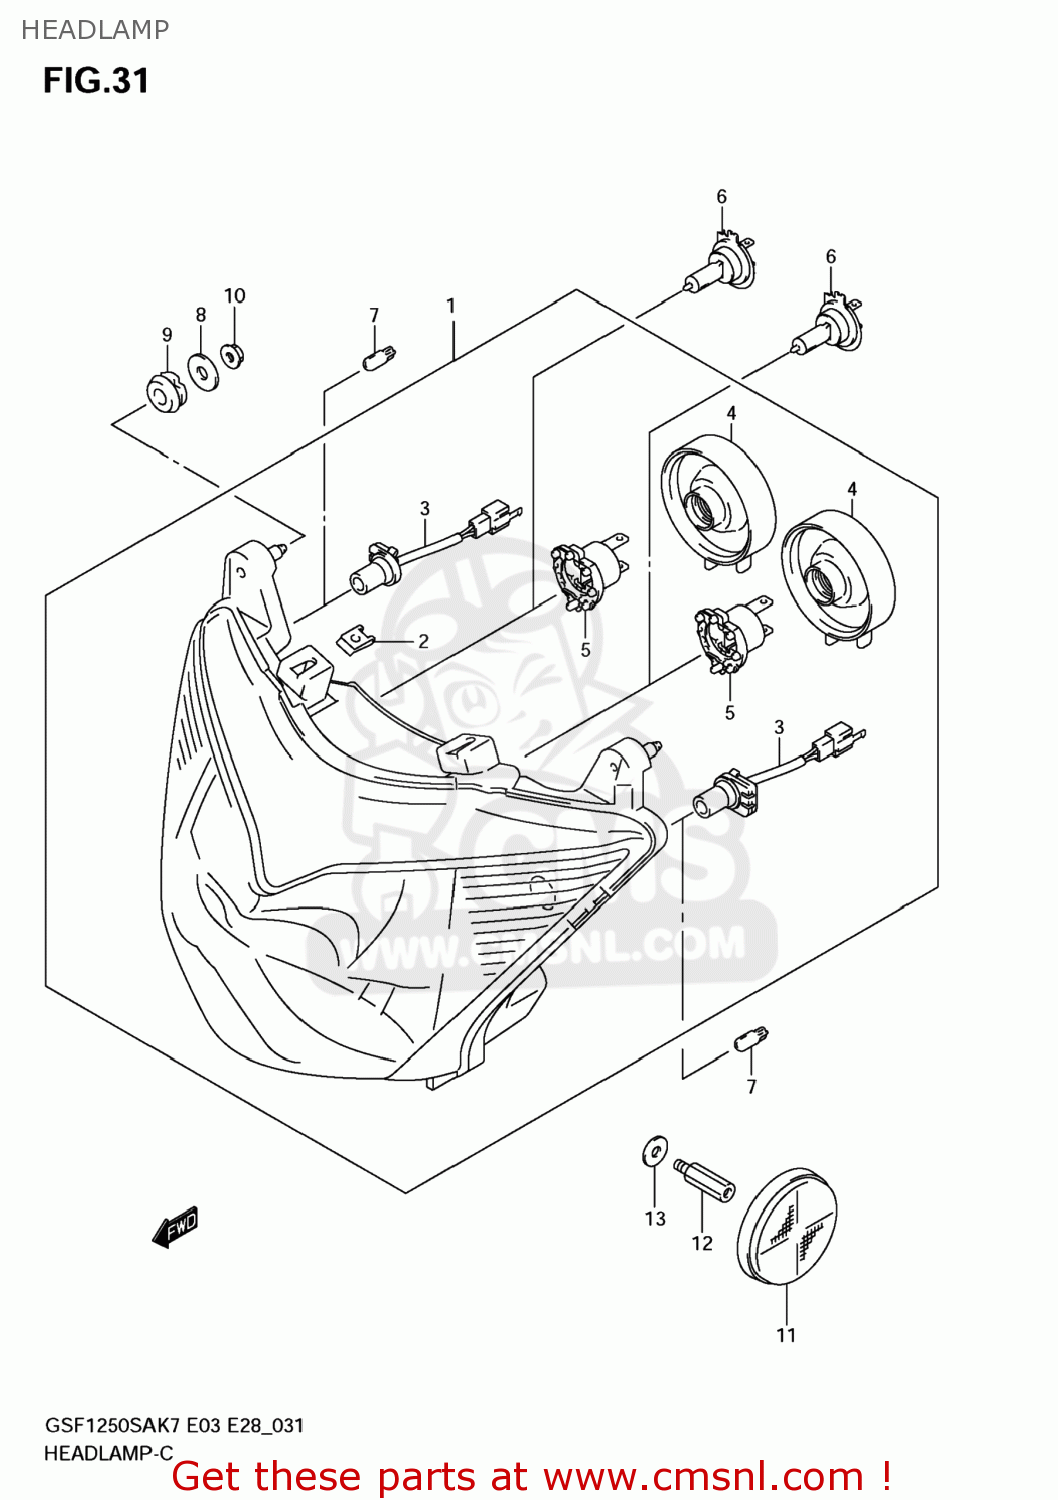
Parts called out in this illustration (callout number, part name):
1	HEADLAMP ASSY
2	NUT,COWL
3	CORD ASSY
4	SOCKET,COVER
5	ADAPTER ASSY
6	BULB(12V55W/H7/PX26D/PHILIPS)
7	BULB(12V5W)
8	WASHER(6.5X20X1.6)
9	CUSHION
10	NUT
11	REFLECTOR,REFLEX
12	BOLT(5X10)
13	WASHER
